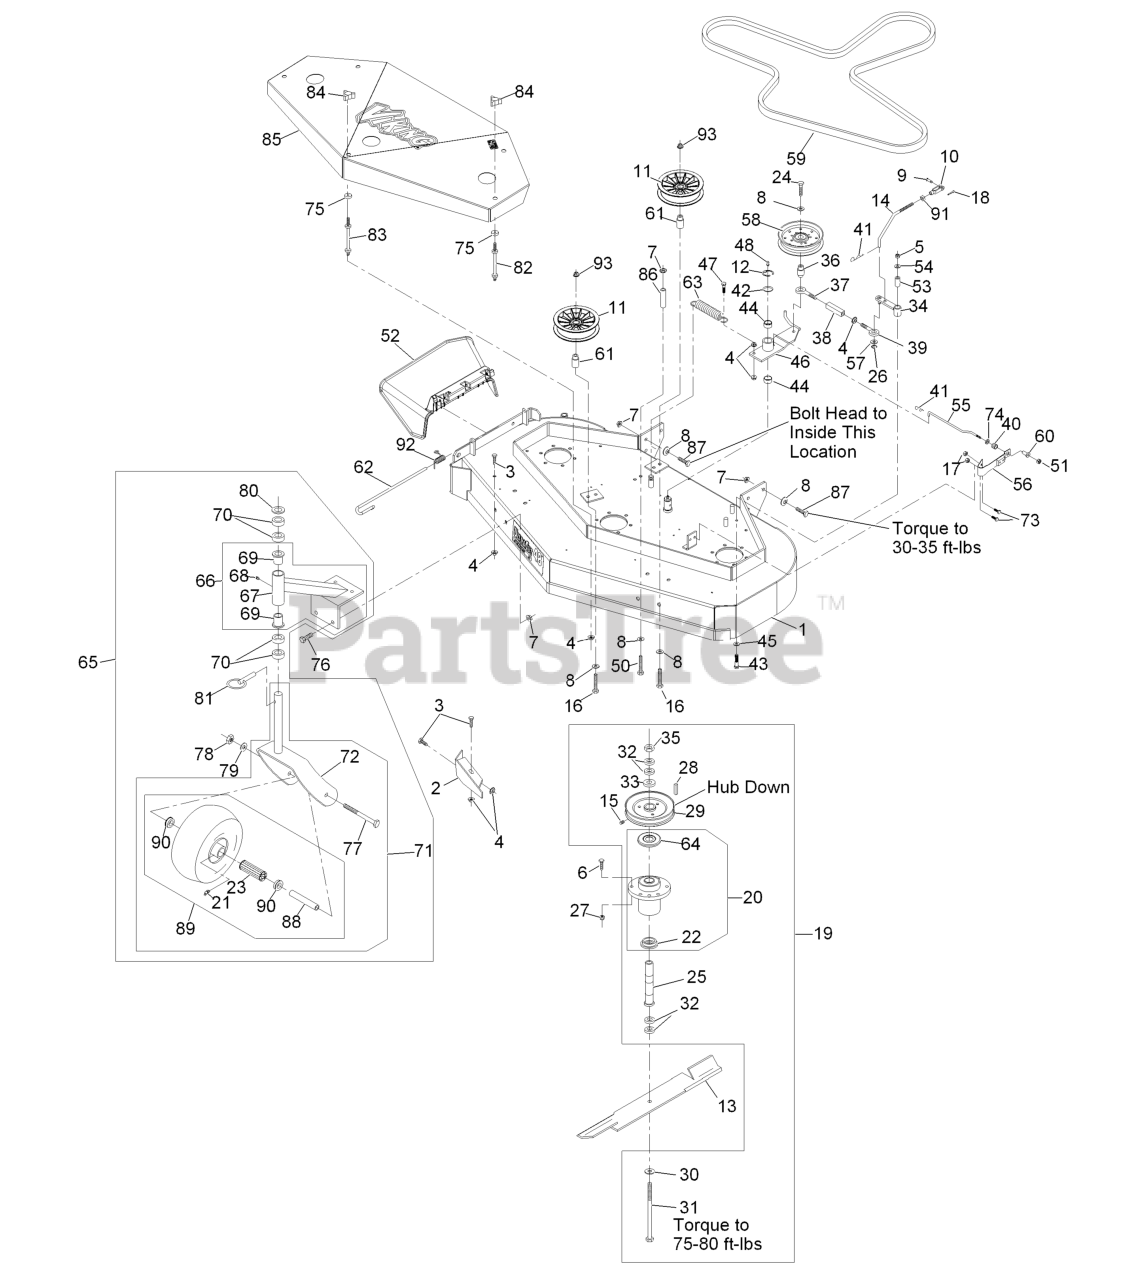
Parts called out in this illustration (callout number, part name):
1	DECK-SERVICE, 48
2	BAFFLE-DOGLEG
3	SCREW-HH
5	NUT-LOCK, NI
6	SCREW-HH
7	NUT-HHF, WHIZ
8	WASHER-BELLEVILLE
9	PIN-CLEVIS
10	YOKE-ADJUSTABLE
11	PULLEY,IDLER 5"
12	RING-RETAINING, EXT
14	ARM-LINKAGE, ASSIST
15	SCREW-SET
15	SETSCREW
16	SCREW-HH
17	NUT-LOCK, NI
18	PIN-COTTER
19	ASM, CUTTER HOUSING OUTER
20	KIT, CUTTER HOUSING
21	FITTING-GREASE
22	SPACER-GUARD, BOTTOM
23	BEARING
24	SCREW-HH
25	TUBE-SPINDLE, SHORT
26	RING-RETAINING, EXT
27	NUT-LOCK, NI
29	SHEAVE
30	WASHER-SPRING
31	SCREW-CAP, HH
33	WASHER-RETAINER, SHEAVE
34	ARM-ASSIST, 32/36
35	NUT-HEX
36	BUSHING-ENGAGEMENT
37	EYEBOLT-THREAD, LH
38	BODY-TURNBUCKLE
39	EYEBOLT-THREAD, RH
40	SPRING-COMPRESSION
41	PIN-COTTER
42	WASHER-SPINDLE
43	SCREW-HH
44	SLEEVE-BEARING
45	WASHER-SPRING
46	IDLER ARM ASM
47	SCREW-HH, SPECIAL
48	FITTING-GREASE
50	SCREW-HH
51	NUT-LOCK, NI
52	CHUTE DEFLECTOR XRK M056
53	TUBE-PIVOT
54	WASHER-FLAT
55	ROD-BRAKE
56	PAD AND SPRING ASM
57	WASHER-PLAIN
59	BELT,BLADE 48
60	SPACER-FLANGED
61	BUSHING-IDLER
62	PIN-CHUTE
63	SPRING-EXTENSION
64	GUARD-BEARING, TOP
66	ASM,CSTR SUPPORT W/WEIGHT
68	FITTING-GREASE
69	BEARING-FLANGED
70	SPACER-CASTER
71	ASM,CASTER/WHEEL
73	SCREW-HH
74	RING-PUSH ON
76	SCREW-HH
77	SCREW-HH
78	NUT-HH
79	WASHER-LOCK
80	WASHER-FLAT
82	STUD-SHIELD, BELT (SHORT)
83	STUD-SHIELD, BELT (LONG)
84	KNOB-3 PRONG
85	ASM,SHIELD W/DECALS 48 VI
87	SCREW-HH
89	KIT, SP CASTER WHEEL REPL
90	BUSHING
91	NUT-HEX
92	SPRING, TORSION
93	NUT-HF, NI
